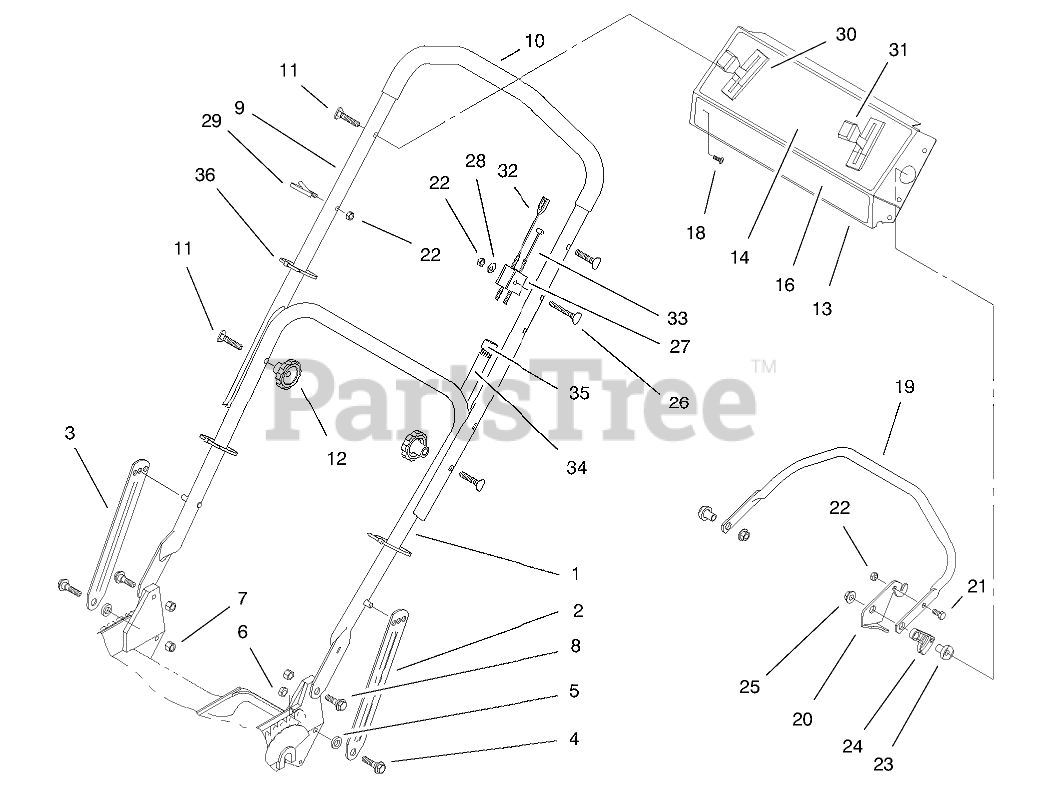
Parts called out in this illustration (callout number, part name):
1	ASM-Handle
2	Latch-Handle
3	Latch-Handle
4	SCREW-SHOULDER
5	SPACER
6	NUT-LOCK, NI
7	Nut-Lock
8	SCREW-SHOULDER
9	Handle-Upper
10	Grip-Foam
11	SCREW-HANDLE
13	Panel-Control (Incl. Ref. #14)
14	DECAL - INSTRUCTION
16	DECAL - CONSOLE
18	SCREW-TAP
19	Bar-Control
20	Lever-Control
21	SCREW-HH
22	NUT-LOCK, NI
23	SPACER-SUPPORT
24	LEVER-TRACTION
25	NUT-LOCK NI
26	SCREW-HANDLE
27	SUPPORT-CABLE
28	WASHER-FLAT
29	GUIDE-ROPE
30	CONTROL-SPEED, GROUND
31	THROTTLE CONTROL
32	BRAKE CONTROL
33	CABLE-TRACTION
34	CONTROL CABLE COVER
35	FITTING-RING
36	TIE-CABLE
